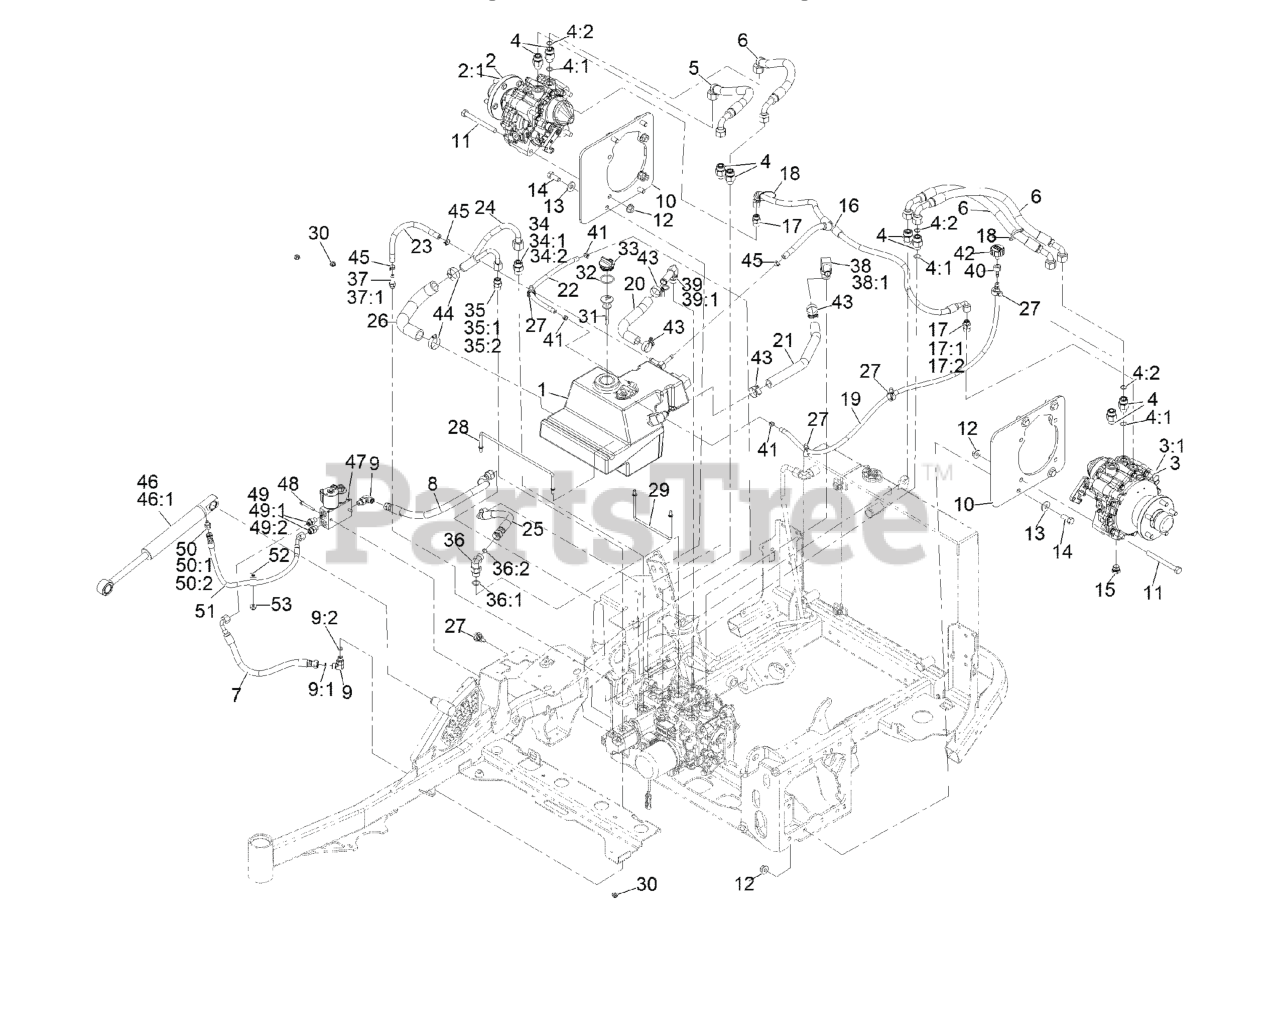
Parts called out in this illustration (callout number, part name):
1	HYD RESERVOIR ASM
2	MOTOR-HYD, RH
2:1	5 STUD WHEEL HUB KIT
3	MOTOR-HYD, LH
3:1	5 STUD WHEEL HUB KIT
4	FITTING-STRAIGHT
4:1	O-RING
5	HOSE ASM
6	HOSE ASM
7	HOSE ASM
8	HOSE ASM
9	FITTING-ELBOW, 90 DEG
9:1	O-RING
9:2	O-RING
10	PLATE-MOTOR
11	SCREW-HH
12	NUT-HHF
13	WASHER-SPRING
14	SCREW-HH
15	PLUG-MAGNETIC
16	TEE HOSE ASM
17	FITTING-STRAIGHT
17:1	O-RING
17:2	O-RING
18	TIE-CABLE
20	HOSE-RETURN
21	HOSE-RETURN
24	TUBE ASM
25	HOSE ASM
26	HOSE-SUCTION
27	CLIP-TIE
28	ROD-SUPPORT, HYD TANK
29	ROD-SUPPORT, HYD TANK
30	NUT-HF, NI
31	DIPSTICK
33	PLUG-PLASTIC
34	FITTING-STRAIGHT
34:1	O-RING
34:2	O-RING
35	FITTING-STRAIGHT
35:1	O-RING
35:2	O-RING
36	FITTING-ELBOW, 90 DEG
36:1	O-RING
36:2	O-RING
37	ADAPTER-STRAIGHT
37:1	O-RING
38	FITTING-ELBOW, 90
38:1	O-RING
39	FITTING-90
39:1	O-RING
40	FITTING-STRAIGHT
41	CLAMP-HOSE
42	BREATHER
43	CLAMP-HOSE
44	CLAMP-HOSE
45	CLAMP-HOSE
46	CYLINDER-LIFT
46:1	CYL Repair Kit
47	DECK LIFT VALVE ASM
48	SCREW-HWHTF
49	FITTING-STRAIGHT
49:1	O-RING
49:2	O-RING
50	FITTING-HYD, STRAIGHT
50:1	O-RING
50:2	O-RING
51	HOSE ASM
52	CLIP-LOOM
53	NUT-HF, NI
